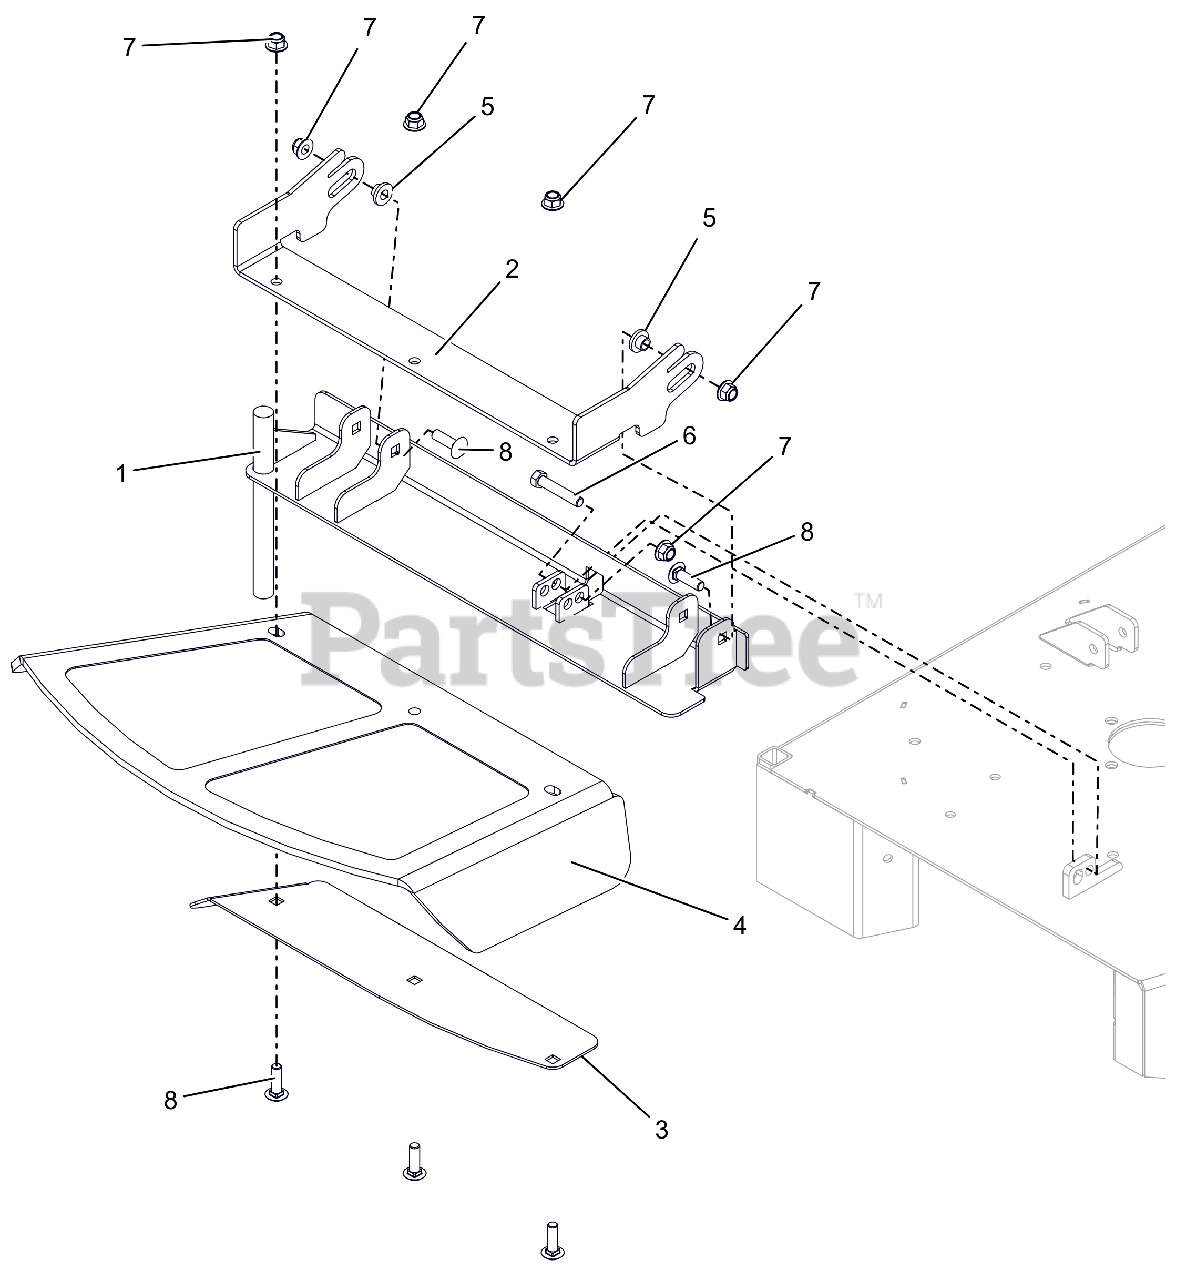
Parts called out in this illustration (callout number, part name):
1	48-60 DISCH CHT MTG WMT W/SAFE
2	48-60" CHUTE MTG BRKT - RED
3	48-60 DISCH CHUTE CLMP PLT-RED
4	CHUTE,48-60" FRMD RUBBER DISCH
5	BSHG-FLG .385X.500X.875X.406
6	BLT,HEX .38-16X2.00 G5 ZCC
7	NUT,NYL-FLG .38-16 GF ZCC
8	BLT,RHSSN .38-16X1.25 G5 ZCC
